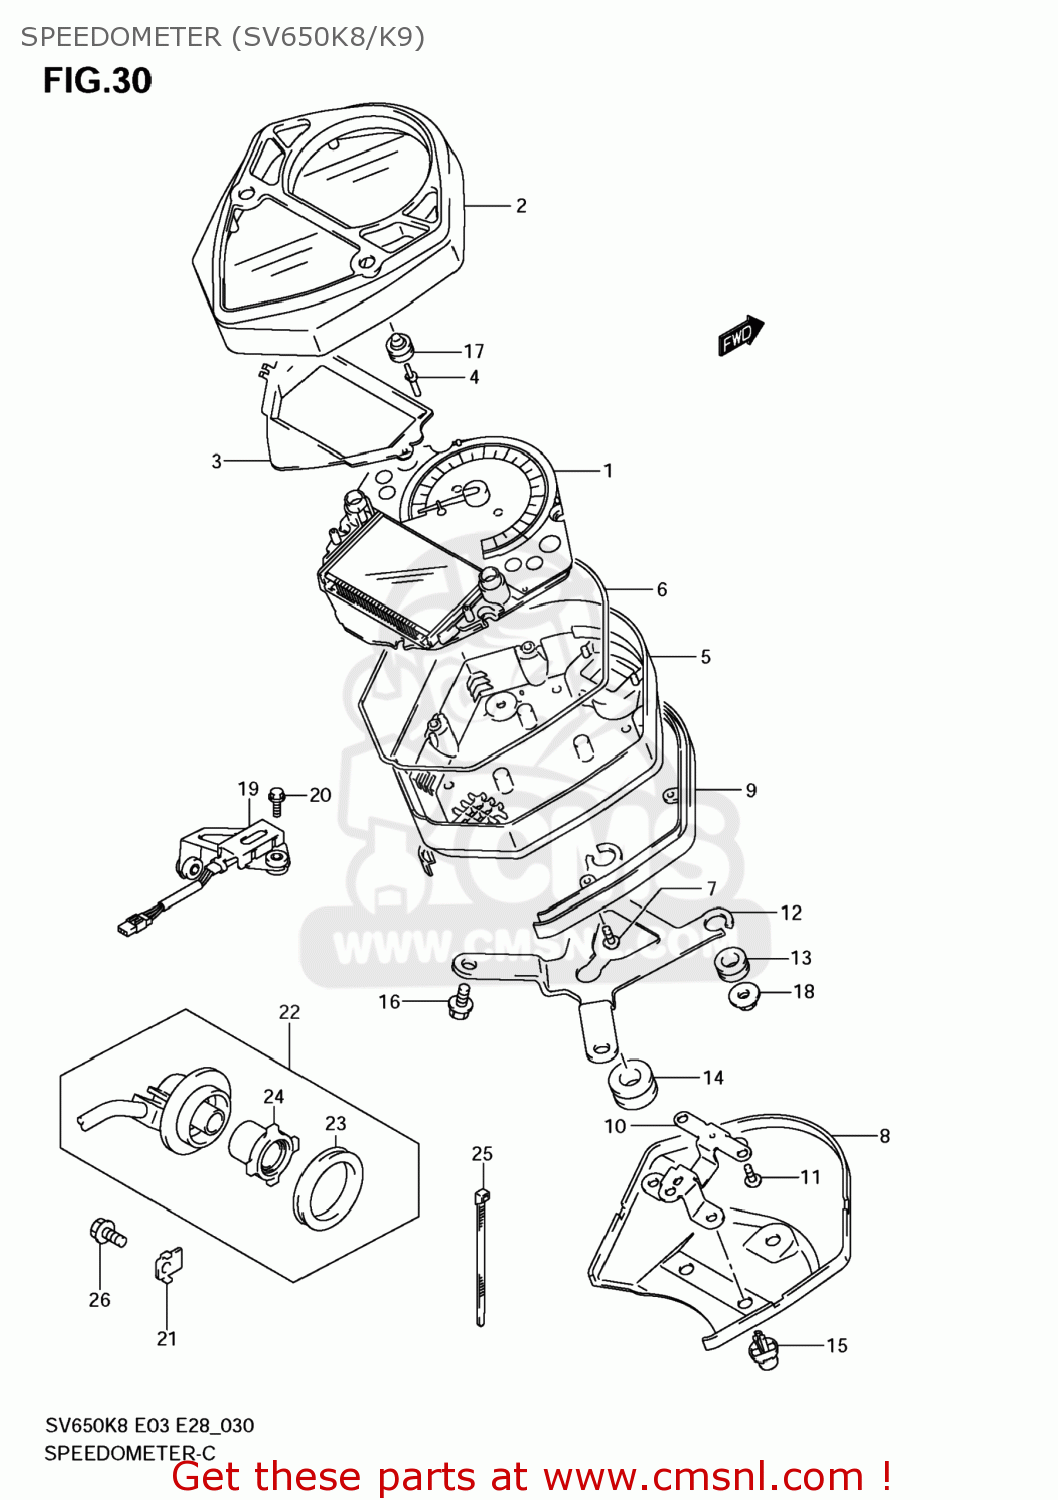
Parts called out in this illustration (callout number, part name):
1	SPEEDOMETER
2	CASE,SPEEDOMETER UPR
3	PLATE,SPEEDOMETER
4	KNOB,SPEEDOMETER
5	CASE,SPEEDOMETER LWR
6	GASKET,METER CASE (NAS)
7	SCREW,SPEEDOMETER
8	COVER,SPEEDOMETER LWR
9	DECORATION PLATE,METER CASE
10	HOLDER,SPEEDOMETER
11	SCREW(4X14)
12	BRACKET,SPEEDOMETER CASE
13	CUSHION,METER
14	CUSHION
15	CLIP
16	BOLT
17	COVER,SPEEDOMETER KNOB
18	NUT
19	RESISTOR ASSY
20	BOLT(6X25)
21	GUIDE,SENSOR LEAD
22	SENSOR,SPEED
23	SEAL,OIL(44X55X6)
24	MAGNETO
25	CLAMP(L:100)
26	BOLT
